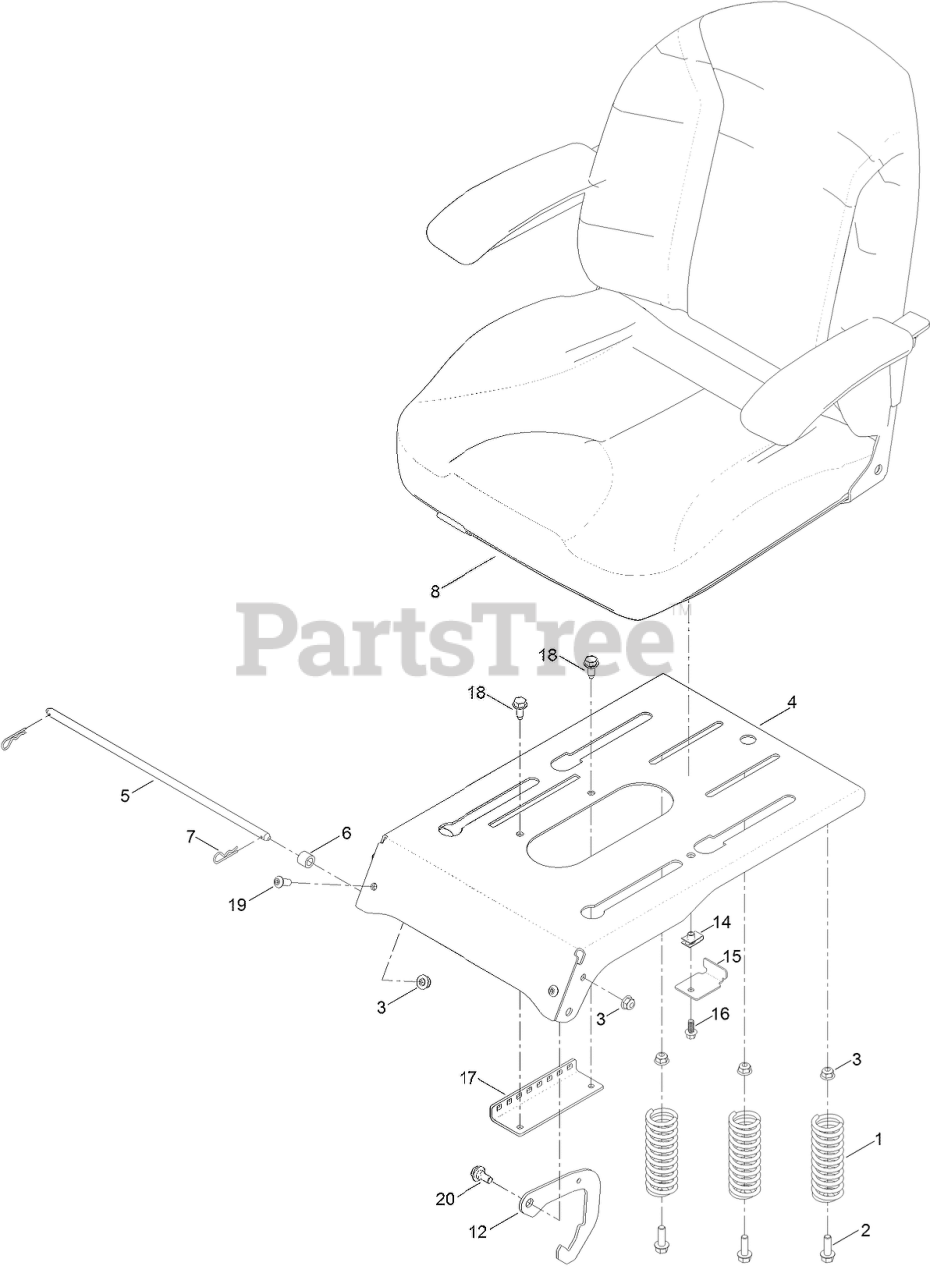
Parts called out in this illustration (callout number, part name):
1	SPRING-COMPRESSION
2	SCREW-HHF
3	NUT-HF, NI
4	PAN-SEAT, DELUXE
5	ROD-STOP
6	BUSHING-LEVER, LIFT
7	PIN-COTTER
8	SEAT ASM
12	LATCH-SEAT
15	BRACKET-STOP, SEAT
16	SCREW-HHF
17	BRACKET-LATCH, SEAT
18	SCREW-HWHTF
19	SCREW-HSBH
20	SCREW-SHOULDER
